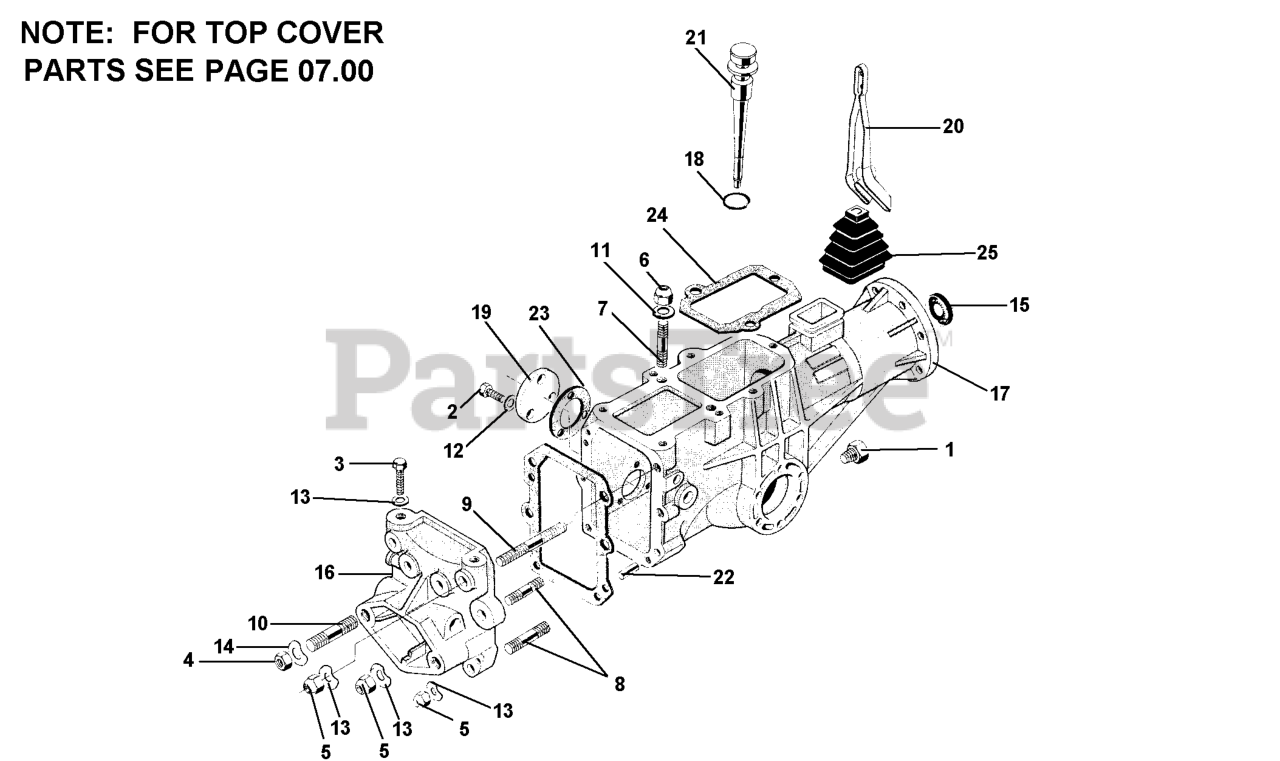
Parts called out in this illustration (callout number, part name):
1	PLUG 1/4 GAS
2	SCREW M6 X 10
3	SCREW M8 X 20
4	NUT M12 X 1.25
5	NUT, SELFLOCKING M8
7	STUD M8 X 38 X 14 X 20
8	STUD M8 X 46 X 16 X 16
9	STUD M8 X 58 X 16 X 16
11	SUPER WASHER 8 DIN 6796
12	WASHER, LOCK 6.4
13	WASHER, LOCK 8.4
14	WASHER, LOCK 13
18	RUBBER RING
20	CLUTCH LEVER
21	CAP, WITH DIP STICK
22	PARALLEL PIN D 6 X 20
24	GASKET, COVER
26	COVER GASKET
